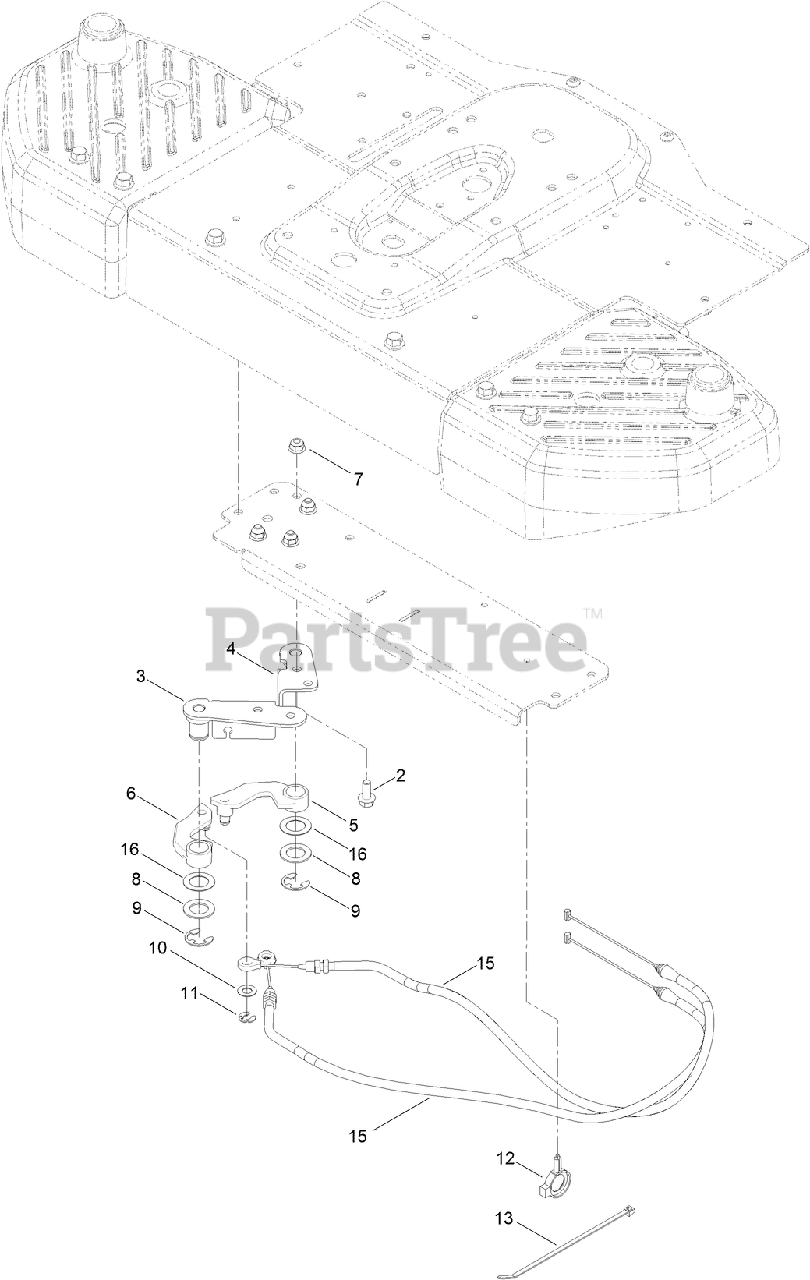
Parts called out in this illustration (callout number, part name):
2	SCREW-HHF
3	CABLE BRACKET ASM
4	CABLE BRACKET ASM
5	ARM-CABLE, RH
6	ARM-CABLE, LH
7	NUT-HF, NI
8	WASHER-THRUST
9	E-RING
10	WASHER-THRUST
11	RING-RETAINING
12	CLAMP-HOSE
13	TIE-CABLE
15	CABLE-STEERING
16	WASHER-THRUST
